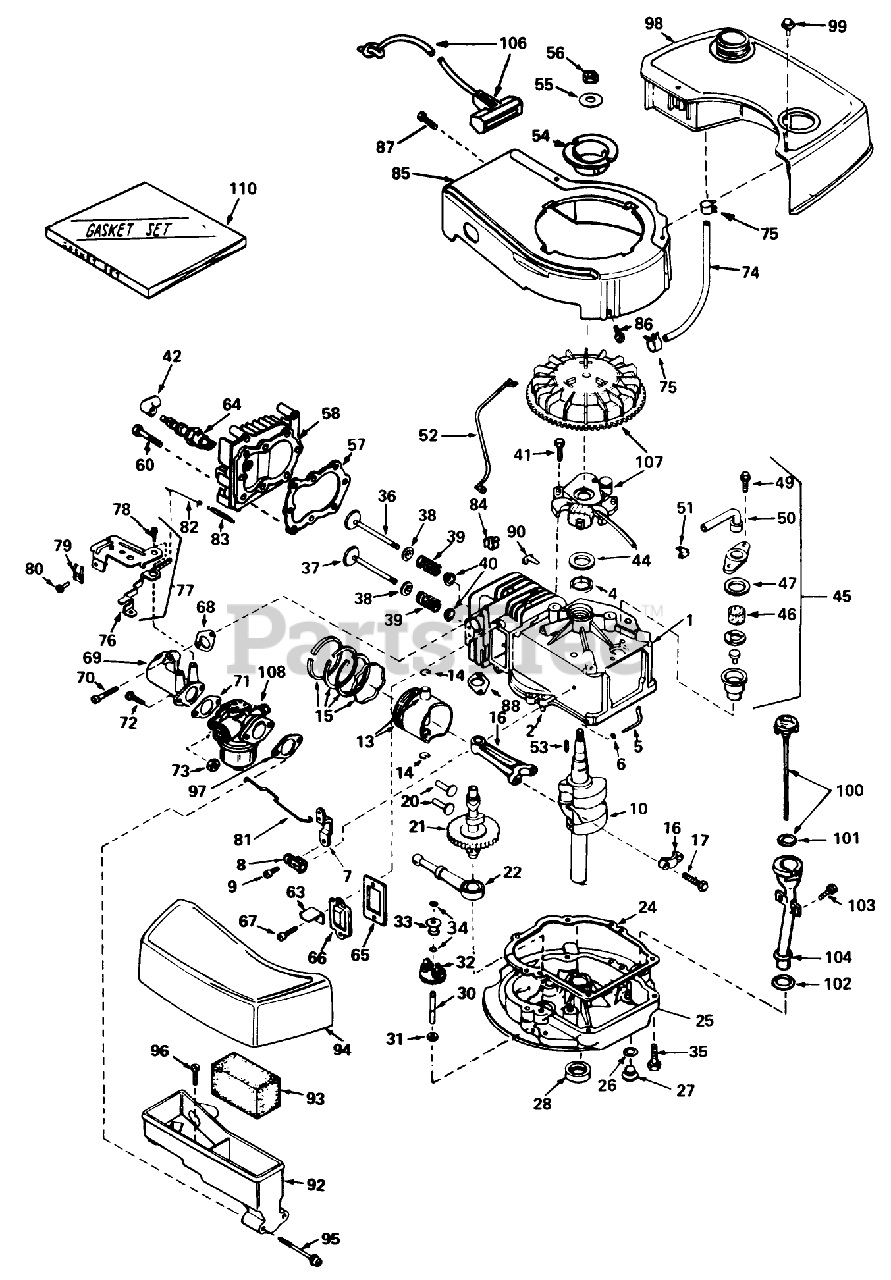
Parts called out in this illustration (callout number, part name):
1	Cylinder Assy. (Incl. Ref. #2, 4 105)
2	Pin-Dowel
4	OIL SEAL
5	Rod, Governor (Incl. No. 36)
6	Washer-Flat
7	Governor Lever
8	Clamp-Lever, Governor
9	Screw
10	Crankshaft
13	Piston, Pin Ring Assy. (Incl.Ref. #14 15)(Std.)
13	Piston, Pin Ring Assy. (Incl. #14 15)(.010 oversize)
13	Piston, Pin Ring Assy. (Incl.Ref. #14 15) (.020 oversize)
14	Ring-Retaining, Piston Pin
15	Ring Set Piston (Std.)
15	Ring Set Piston (.010 Oversize)
15	Ring Set Piston (.020 Oversize)
16	Rod Assy., Connecting (Incl. Ref. #17)
17	Bolt-Rod, Connecting
20	Lifter-Valve
21	Camshaft(Mech.Comp. Release)
22	Oil Pump ASM
24	Gasket, Mounting
25	Flange Assy., Mounting (Incl. Ref. #26thru 30)
26	Gasket-Oil Drain
27	Plug Oil Drain
28	Seal Oil
30	Shaft-Governor
31	Washer-Flat
32	Governor Gear ASM
33	Spool-Governor
34	Ring-Retaining
35	Screw (1/4-20 x 1-1/4)
36	Valve, Intake (Incl. Ref. #38, 39 40) (Std.)
36	Valve, Exhaust (1/32" Oversize) (Incl. Nos. 8, 9 10)
37	Valve, Exhaust (Standard) (Incl. Nos. 8, 9 10)
37	Valve, Exhaust (1/32" Oversize) (Incl. Nos. 8, 9 10)
38	Cap-Upper Valve Spring
39	Spring-Valve
40	Cap-Valve, Spring
41	Screw
42	Cover-Spark Plug
44	Gasket Stator
45	Breather Assy. (Incl. Ref. #46, 47, 49, 50 51 )
46	Element-Breather
47	Gasket-Breather
49	Screw, Hex Hd. w/Conical
50	Tube, Breaker
51	Clip, Breather
52	Wire, Ground
53	Key-Flywheel
54	Pulley Starter
55	Washer-Spring
56	Hex Nut
57	63573 GIL 42 SNWTHW
58	Head-Cylinder
60	Screw (5/16-18x1-1/2)
63	Retainer Clip
64	Plug, Spark (J17LM or equiv.)
64	Plug, Spark (Champion RCJ-8)
65	Gasket-Breather
66	Cover-Valve
67	Screw
68	Gasket, Intake
69	Pipe, Intake
70	Screw (1/4-20 x 1)
71	Gasket-Carburetor
73	Nut and Lock Washer (1/4-28)
74	Line-Fuel
75	Clamp-Line, Fuel
76	Lever Control
77	Control Assy., Speed (Incl. Nos, 76, 78 89)
78	Screw, Hex Washer Hd Shoulder Self-Tap
79	Conduit
80	Screw (10-32 x 3/8)
81	Link-Throttle
82	Link Governor Spring
83	Spring Governor
84	51004 GIL ROTARY TI
85	Housing Blower
86	Screw
87	Screw (10-24 x 9/16)
88	Gasket Exhaust
90	Clip-Wire
92	Body Air Cleaner
93	Filer, Air
94	Cove, Air Cleaner
95	Screw Fil Hd.
96	Screw, Hex Hd.
97	Gasket-Air Cleaner
98	Tank, Fuel
99	Screw (10-32 x 35/64)
100	Dipstick, Oil (Incl. Ref. #101)(Twist Lock)
101	O-Ring
102	Gasket
103	Screw (10-32 x 1/2)
104	Tube-Oil Fill
106	Rope Assy., Starter
107	Magneto
108	Carburetor (Incl. Ref. #71 )
110	53024/VAR.16HP O/P
